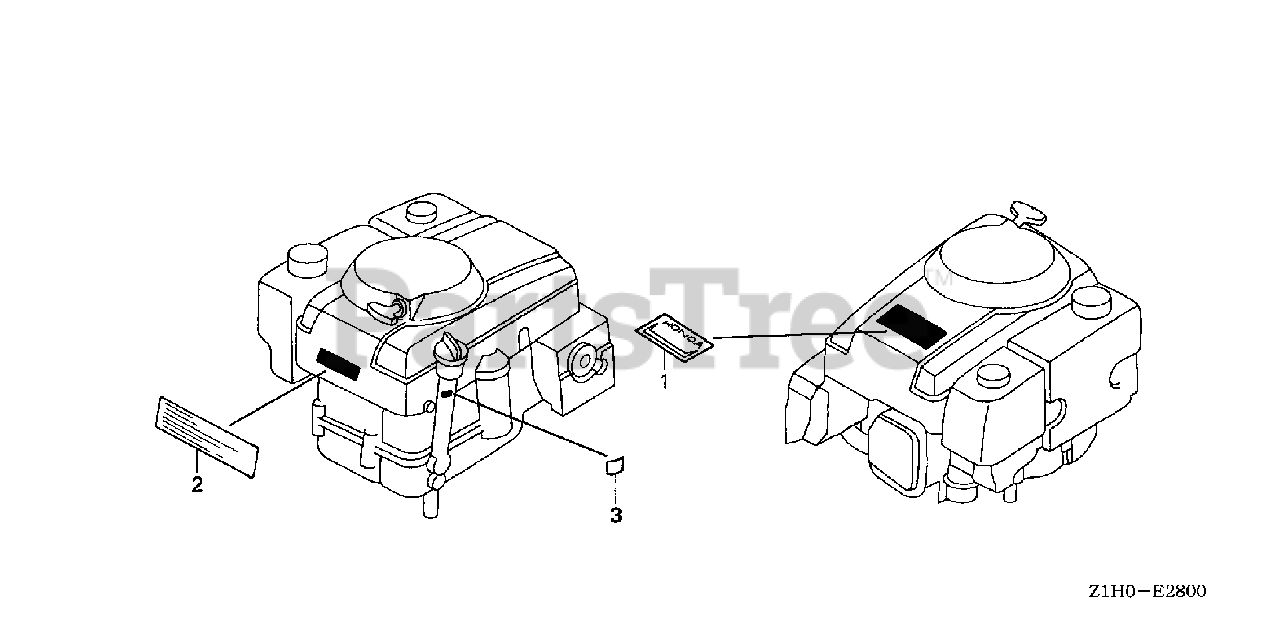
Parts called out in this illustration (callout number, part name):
1	EMBLEM, TOP COVER (11.0)
2	LABEL, CAUTION
3	MARK, TYPE (DAS)
